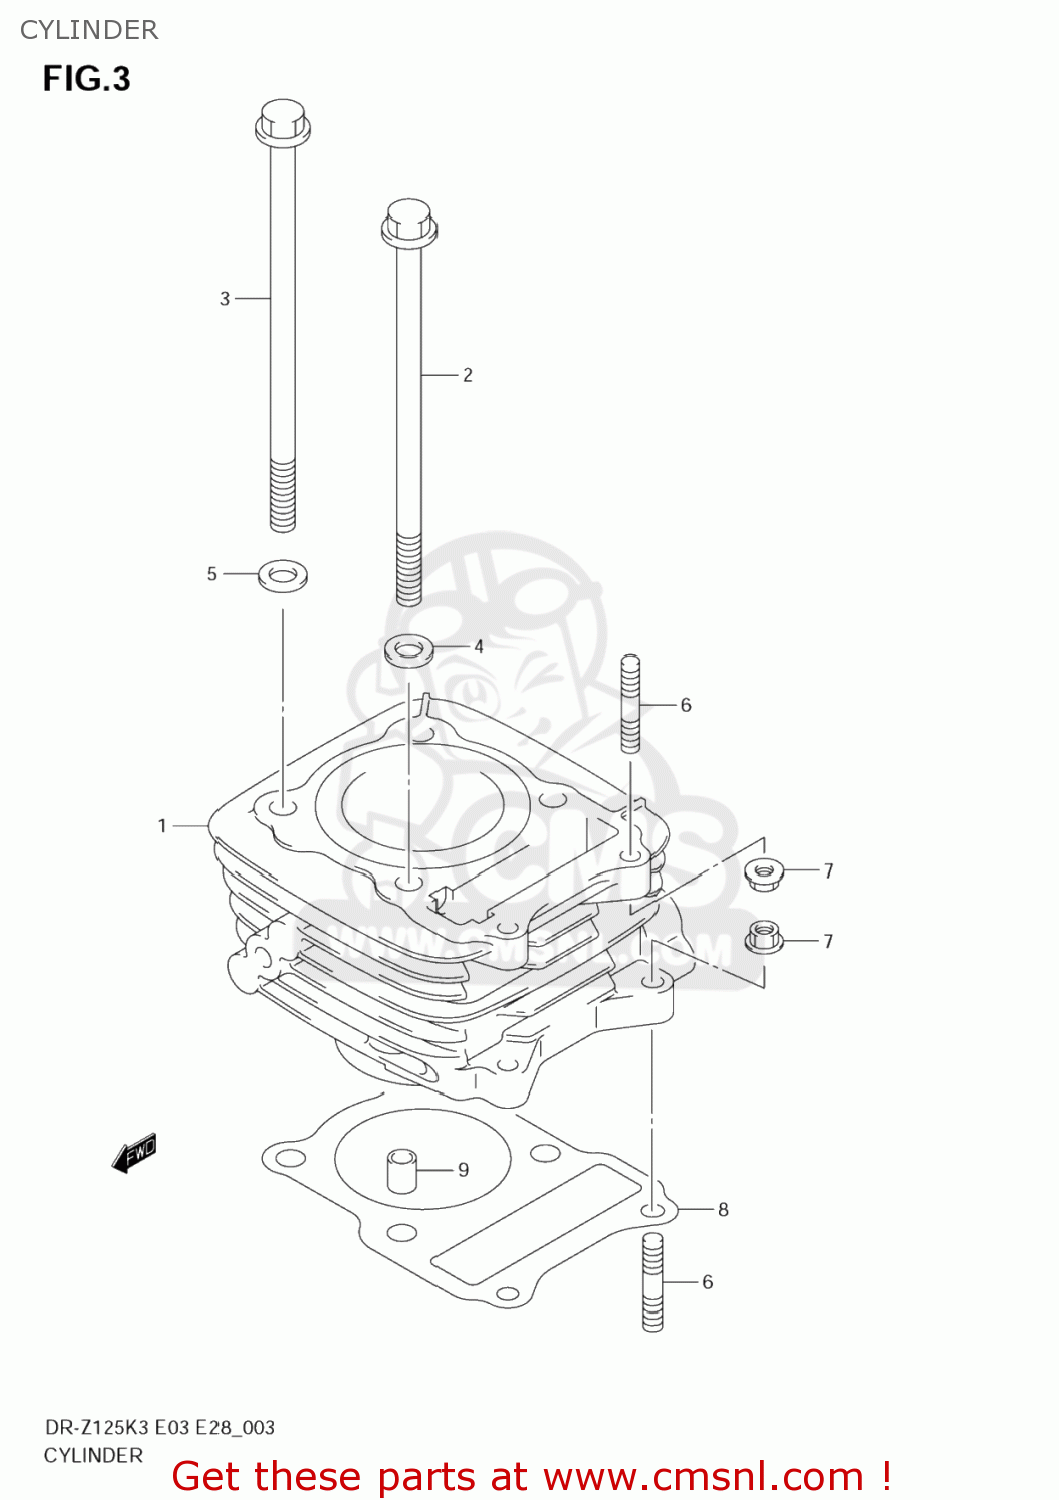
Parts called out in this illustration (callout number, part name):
1	CYLINDER
2	BOLT(8X155)
3	BOLT(8X165)
4	WASHER (8.5X19X2.3)
5	GASKET(8.5X17X2.3) (NAS)
6	STUD BOLT
7	NUT
8	GASKET,CYLINDER (NAS)
9	PIN
